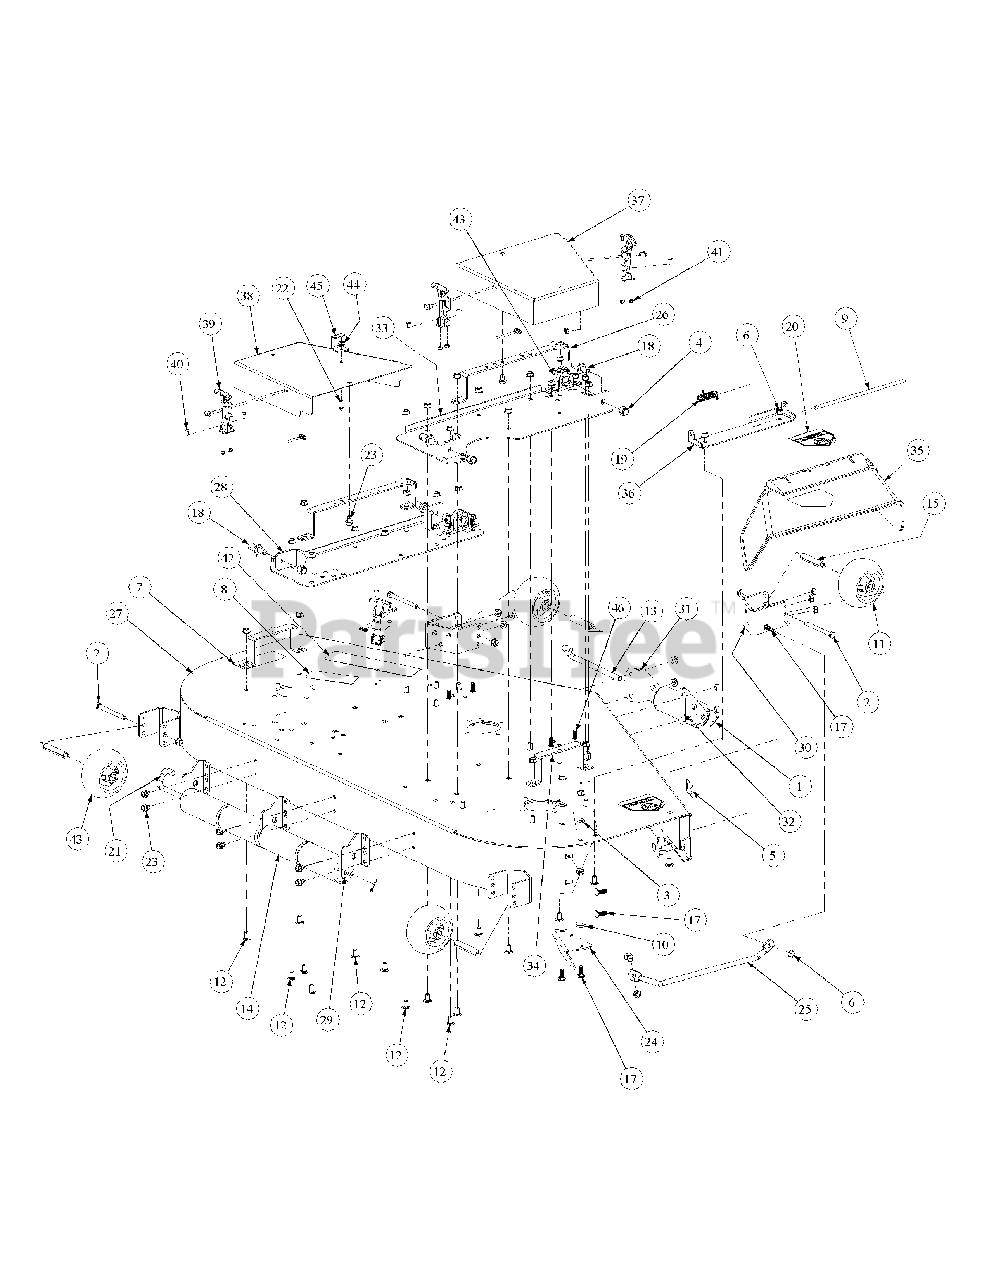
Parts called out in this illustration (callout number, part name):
1	Cotter Pin, .125 Dia. x 1.0
2	Hex Cap Screw, 3/8-16, 3.75
3	Flat Washer, 3/8
4	Lock Nut, Nylon Insert, 1/2-13
5	Label, 60"
6	Flange Lock Hex Nut, 3/8-16
7	Decal, Rotating Blade
8	Decal, Warning Shield Missing
9	Chute Deflector Rod
10	Idler Washer
11	Complete Wheel, 5.00 Dia.
12	Carriage Bolt, 3/8-16 x .75 Lg.
13	Roller Pin, 1/2 Dia. x 7.31 Lg.
14	Front Roller
15	Wheel Spacer
17	Carriage Bolt, 3/8-16 x 1
18	Pin, 5/8 Dia. x 1.2 Lg.
19	Torsion Spring, 0.4ID x 2.16Lg
20	Decal, Danger Hand and Feet
21	Roller Pin
22	Hex Cap Screw, 5/16-18 x .75
23	Hex Index Washer Screw, 3/8-16, .5
24	Chute Bracket
25	Finger Guard
26	Belt Cover Support
27	60" Deck Assembly
28	Left Hand Mount Deck Bracket Assembly
29	Deck Roller Mount Bracket
30	Anti-Scalp Wheel Front Mount Bracket
33	Right Hand Deck Bracket Assembly
34	Outer Belt Cover Support Assembly
35	Chute Deflector
36	Chute Deflector Bracket
37	Right Hand Deck Belt Cover Weldment
38	Left Hand Deck Belt Cover Weldment
39	T-Handle Latch Draw
40	Phillips Head Screw, 10-32
41	Lock Nut, Nylon Insert, 10-32
42	Commercial Mower Label
43	Pillow Block
44	Nut, 5/16-18, Hex Flange Lock
45	Stop Bracket
46	Carriage Screw, 3/8-16 x 1.25
